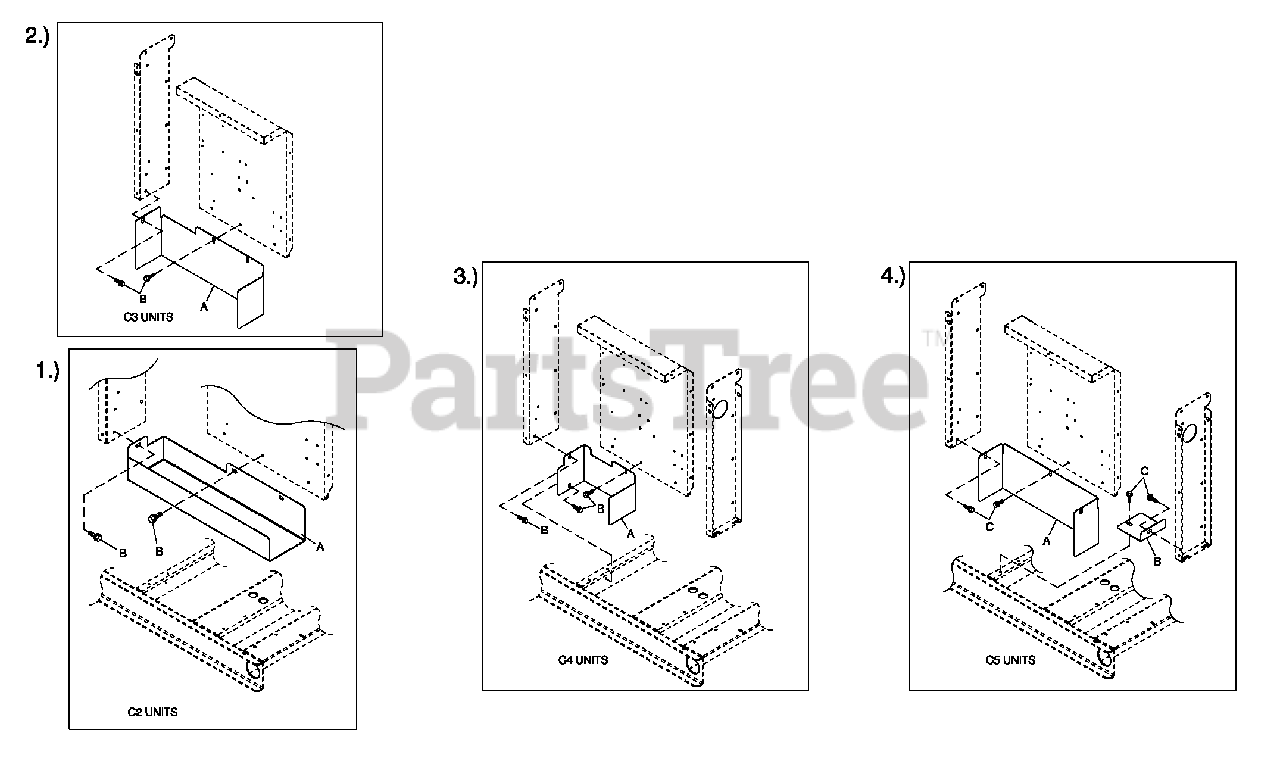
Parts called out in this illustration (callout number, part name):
1	C2 UNITS
2	C3 UNITS
3	C4 UNITS
4	C5 UNITS
A	SHIELD CONN BOXC2
B	SCREW THF M6-1 X 16 N WA Z/JS
A	SHIELD CONTROL STAND C3
A	SHIELD CONTROL STAND C4
A	SHIELD CONTROL STAND C5
B	SHIELD CONTROL STAND C5
C	SCREW THF M6-1 X 16 N WA Z/JS
